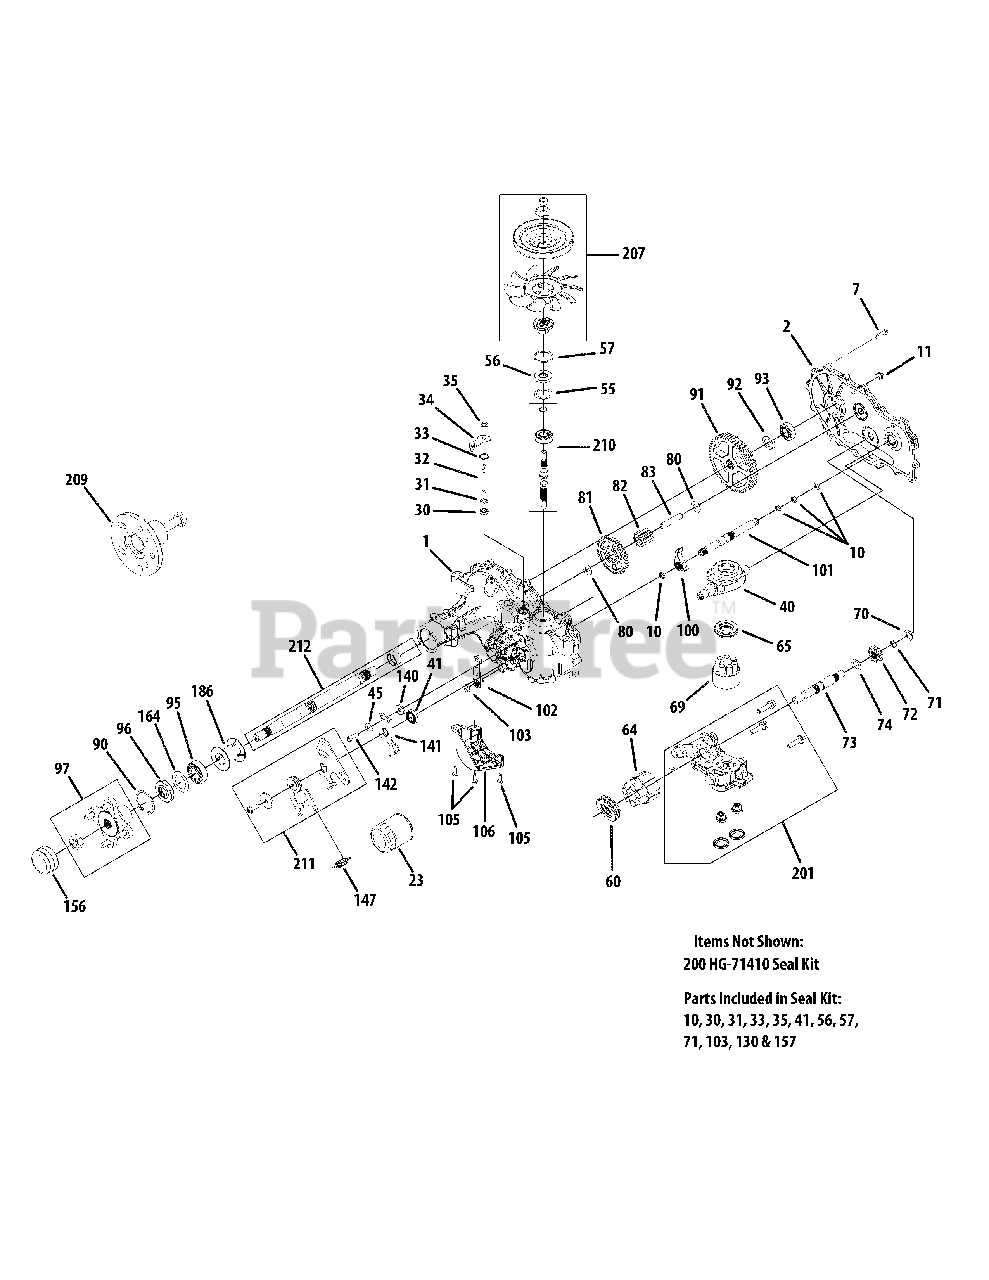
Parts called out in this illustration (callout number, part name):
1	Kit, Main Housing, RH Control
2	Kit, Side Cover, RH
7	Screw, Hex Washer
23	Filter, Spin-On 2.6 x 3.0
30	Seal, Lip, .375 x .75 x .25
31	Ring, Retaining .375 External
32	Rod, Bypass
33	Ring Retaining .750 Internal
34	Arm, Bypass
35	Ring, Ret .375 External
40	Trunnion, Swashplate
41	Seal, Lip 18 x 32 x 7
45	Washer, .34 x .88 x .06
55	Washer, 1.23 x 1.57 x .04
56	Seal, Lip 17 x 40 x 7
57	Ring Retaining Internal
60	Bearing, Thrust 35 x 62 x 18
64	Kit, 16cc Cylinder Block Assembly
65	Thrust Bearing, 30 x 52 x 13
69	Kit, Block, 7 Piston
70	Washer, .63 x 1.00 x .05
71	Ring, Reatining, Motor Shaft
72	Gear, 16T
73	Shaft, Motor
74	Washer, .71 x 1.16 x .04
81	Gear, 43T
82	Gear, 11T
83	Pin, Jackshaft
90	Ring, Retaining 2.25 Internal
91	Gear, 54T
92	Spacer, .750 x 1.00 x .257
93	Bearing, Ball 3/4 x 40mm x 12mm
95	Bearing, Ball 25.4 x 52 x 15
96	Seal, Lip, 1.0 x 2.06 x .38
97	Kit, Hub 4-Bolt
100	Pawl, Brake
101	Kit, Brake Shaft
102	Handle, Actuating
103	Ring, Retaining .438 External
105	Screw, Hex Washer 1/4-20 x .75
106	Guard, Filter, RH
140	Spacer, .320 x 1.005 x .150
141	Arm, Neutral Right
142	Socket Cap Screw, 5/16-24 x 7/8
147	Spring, Extension
156	Cap, Axle
164	Spacer, 1.355 x 2.035 x .021
186	Tube, Axle 2.03
200	Kit. Seal, ZT-2800
201	Kit, Center Section RH
207	Kit, Fan Pulley
207	Fan Only
207	Pulley Hub
209	Kit, Hub Puller
210	Kit, Input Shaft
211	Kit, RTN Bidirectional
212	Kit, Shaft Axle
